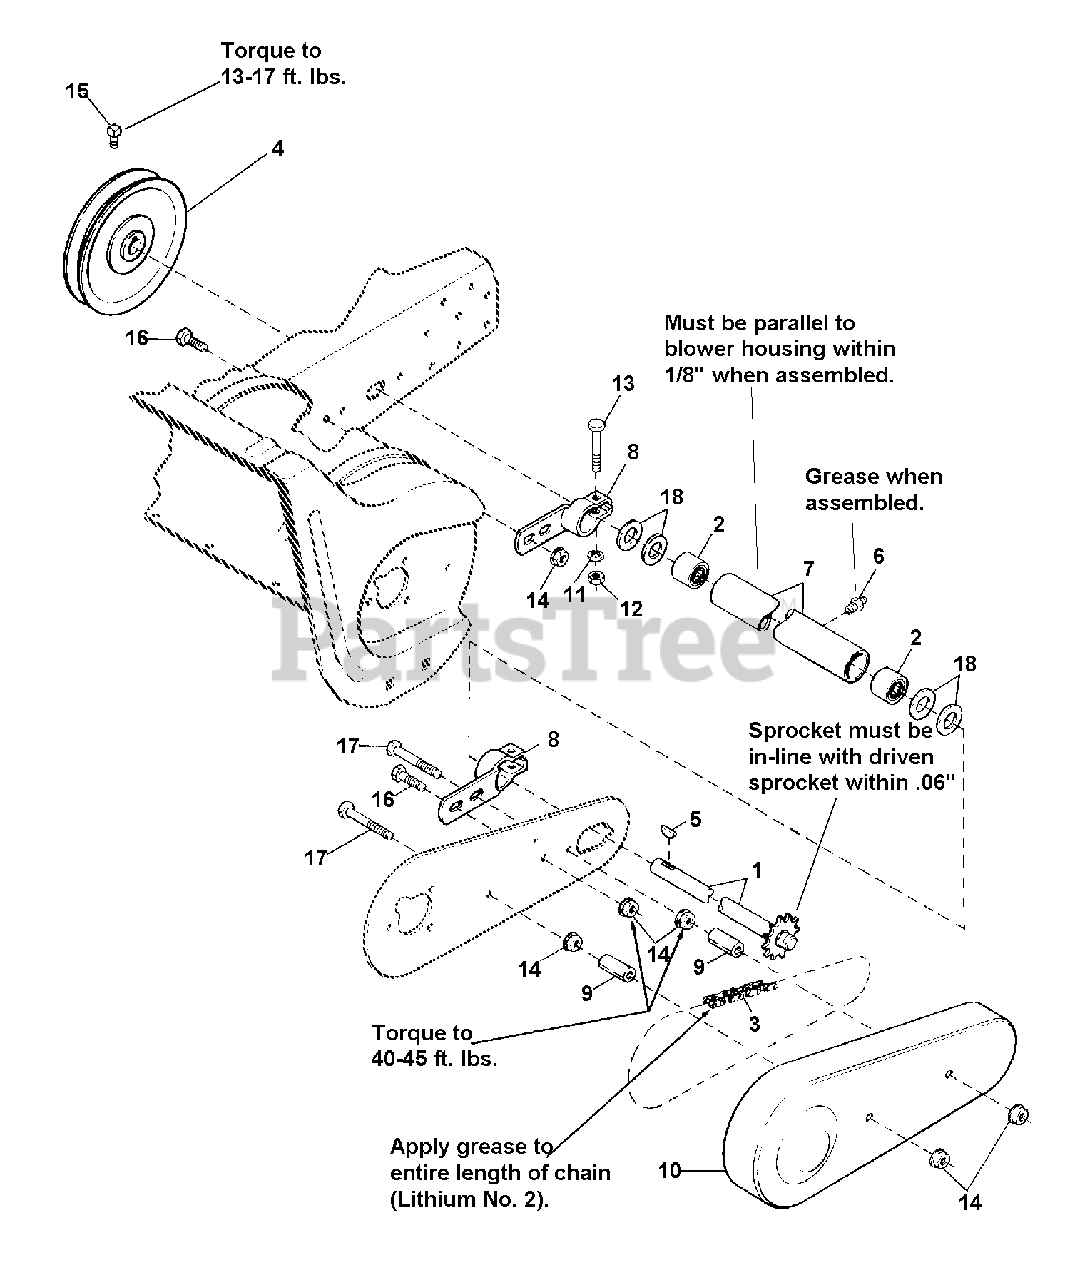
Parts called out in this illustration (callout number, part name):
1	SHAFT ASSEMBLY
2	BEARING, Needle
3	CHAIN (Auger Drive) #40 32" 64 Pitch
5	KEY
6	FITTING, Grease
7	HOUSING ASSEMBLY, w/Bearings (Incl. Ref. No. 2)
10	GUARD, Chain
11	LOCKWASHER, 5/16
12	NUT, Hex, 5/16-18
13	CAPSCREW, Hex Head, 5/16-18 x 1-3/4
14	LOCKNUT, Flange, 5/16-18
15	SETSCREW, 5/16-18 X 1/2
16	CAPSCREW, Hex, Whizlock, 3/8-16 x 1
17	CAPSCREW, Hex, Whizlock, 3/8-16 x 2-3/4
